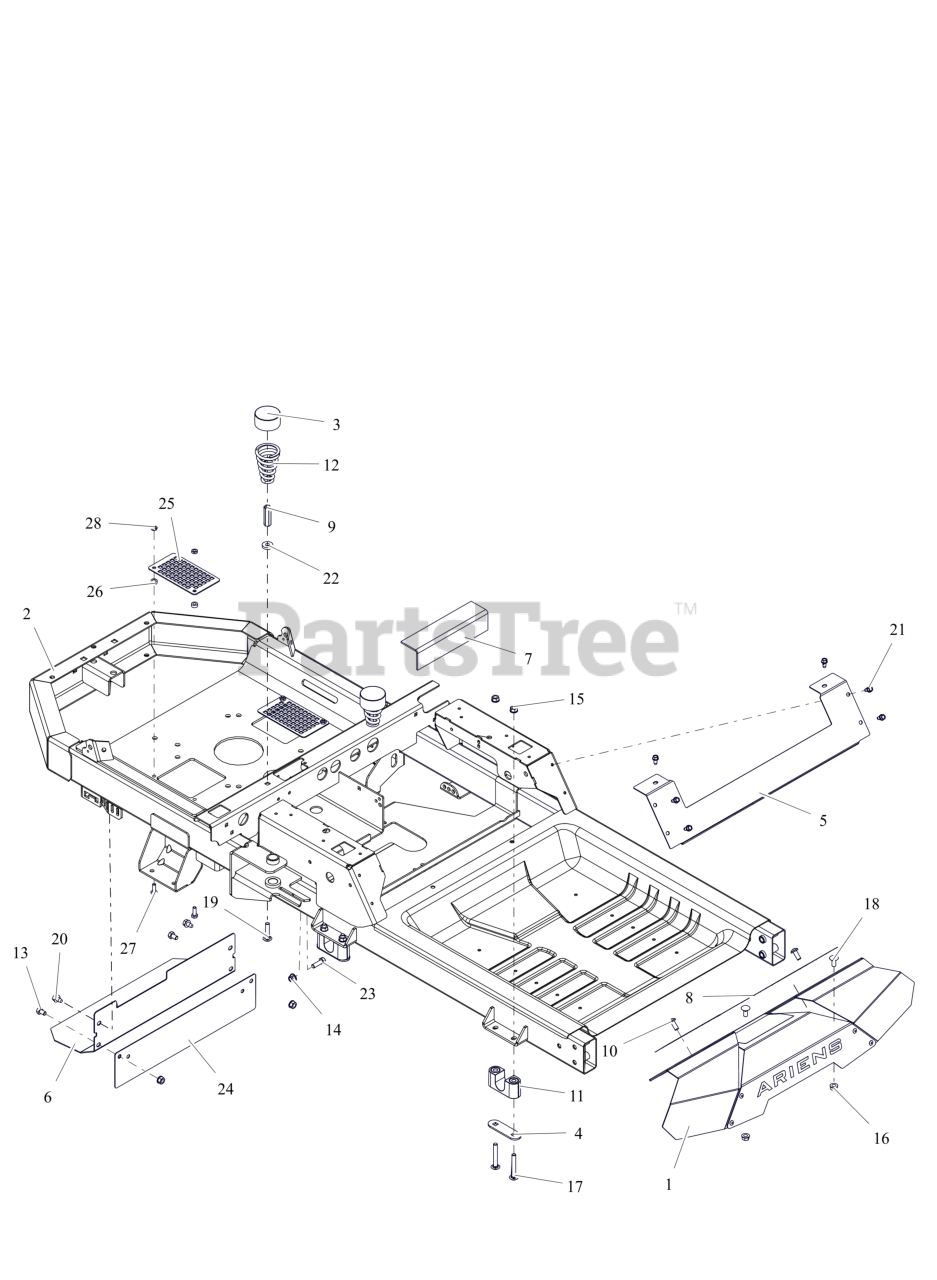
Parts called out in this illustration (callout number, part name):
1	KIT, IKON FOOT REST W/DECAL
2	WLDMT- FRAME - IKON X/XL
3	HUB CAP
4	PLATE, BEARING SUPPORT
5	PLATE, SEAT KICK
6	HEAT, SHIELD
7	PAD, RUBBER-TANK
8	GRIP TAPE, FOOT PLATE
9	NUT, COUPLING .31-18X1.75 ZCC
10	SCR-RDHDSKTAP .31-18X.75 ZCC
11	BSHG, DECK LIFT PIVOT
12	SPRING, SEAT
13	BLT, HEX .31-18X.50 GR5 ZCC
14	NUT,LK-NYL-FLG .31-18 G5ZC120
15	NUT,LK-CTR-FLG .31-18 GF ZCC
16	NUT-LK-TOP-FLG .312-18 GF ZCC
17	BLT, RHSSN.31-18X2.25 G5 ZCC
18	BLT,RHSN .31-18X.75 G5 ZCC
19	BLT,RHSN .31-18X1.50 G5 ZCC
20	SCR,TAP .312-18X.50 HWH TR ZCC
21	SCR-TAP .25-20X.50 HWH ZCC
22	WSHR, FLT .328X.870X.179 ZCC
23	BLT,HEX .31-18X1.00 G5 ZCC
24	GUARD, REAR ,CLUTCH (GREY PEARL)
25	GUARD, VENT - IKON CE
26	BSHG-SLV .265X.500X.219
27	BLT, HEX .25-20X.75 G5 ZCC
28	NUT-LK-CTR-JAM .250-20 GB ZCC
